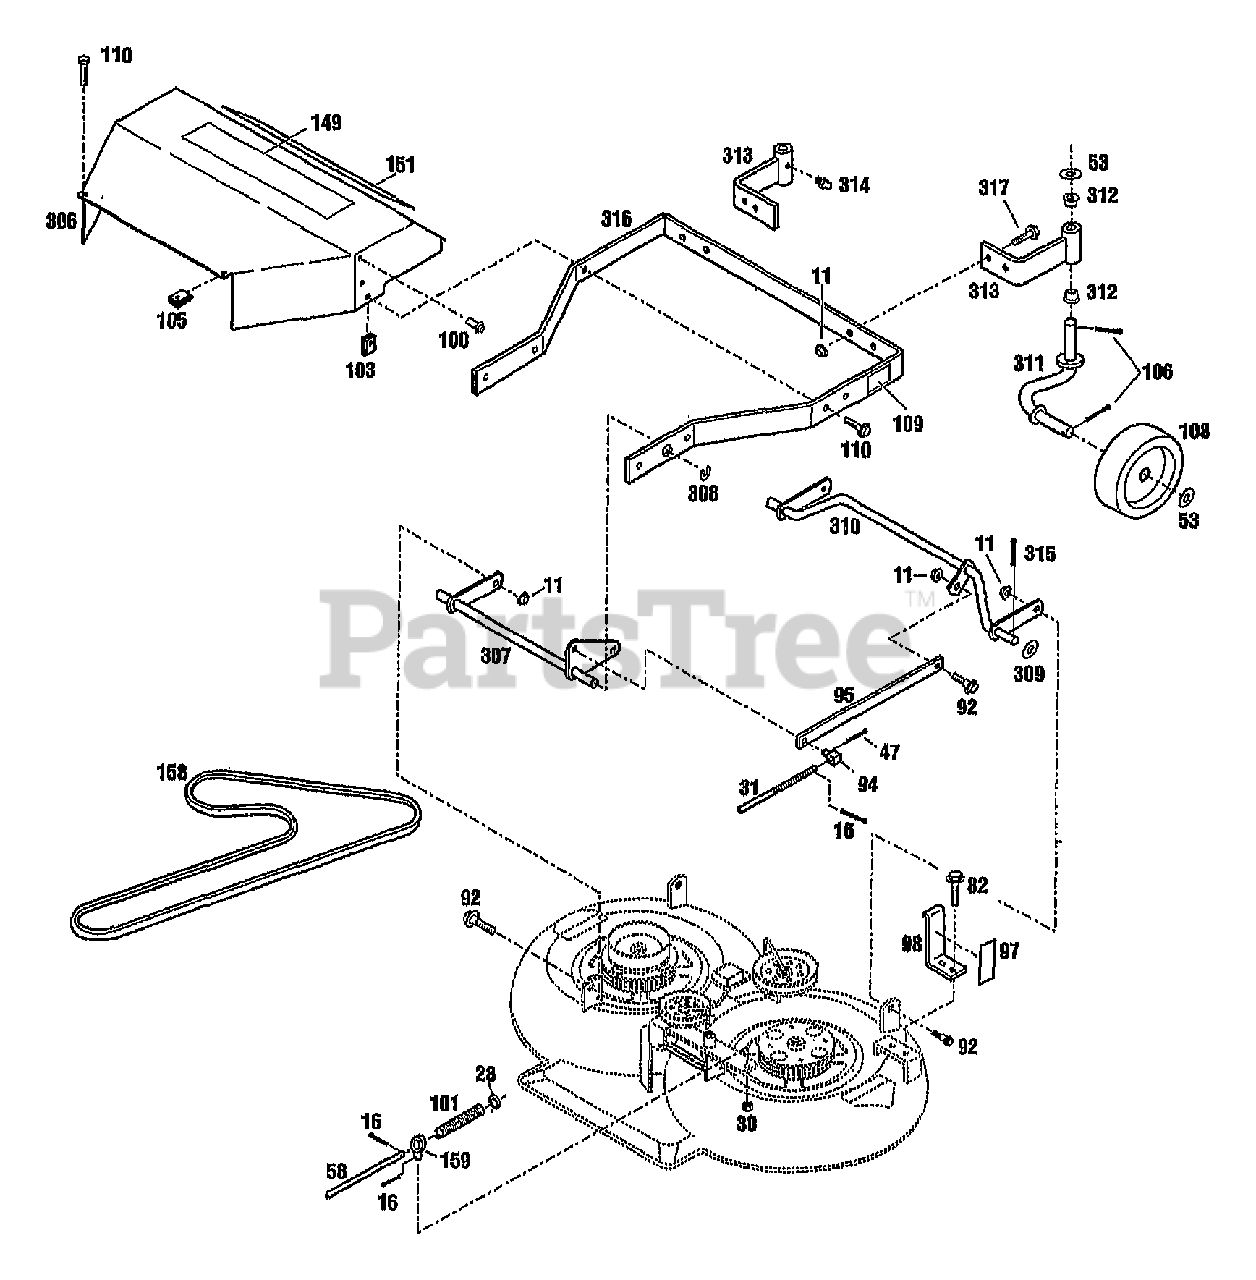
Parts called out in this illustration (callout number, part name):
11	NUT-HFLK 3/8-16 ZP
16	PIN-COTTER .093X.625
28	WASHER-FLAT 3/8 SAE
30	NUT-LOCK 3/8-16
31	ASSM-CRANK LIFT
47	PIN-COTTER .125 X .75 ZP
53	WASHER-1.25X.765X.049
58	ROD-LOWER BLADE
82	SCR 1/4-20X.5 FL SELF TAP
92	SCR-SHLDR 3/8-16X.25 G5ZP
94	BLOCK-PIVOT ZP
95	BAR-LEVELER
97	DECAL-CUTTING HEIGHT
98	BRKT-HEIGHT ADJUSTING
100	RIVET-POP .125
101	SPRING-COMPRESS BLADE ROD
103	NUT 5/16-18 SPEED
105	NUT-SPEED
106	PIN-COTTER .125X1.5
108	GAUGE-WHEEL
109	DECAL-CUT LINE
110	SCR-HFLK 5/16-18X.75 ZP
149	DECAL-TROY BILT
151	DECAL-33" MULCHING
159	BOLT-EYE
165	SCR-SHLDR 3/8-16X.25 G5ZP (WAS 1703051)
306	COVER-BELT
308	RING-RETAINING
309	WASHER-1.0X.64X.029
310	ASSM-FRONT LIFT
311	ASSM-SPINDLE
313	BAR-WHEEL SUPPORT
314	FITTING-GREASE 1/4-28X2.00
315	PIN-COTTER .120X1.25 ZP
316	FRAME-FRONT
317	SCR-HFLK 3/8-16X1.00 ZP
402	PAINT-BLACK SPRAY
